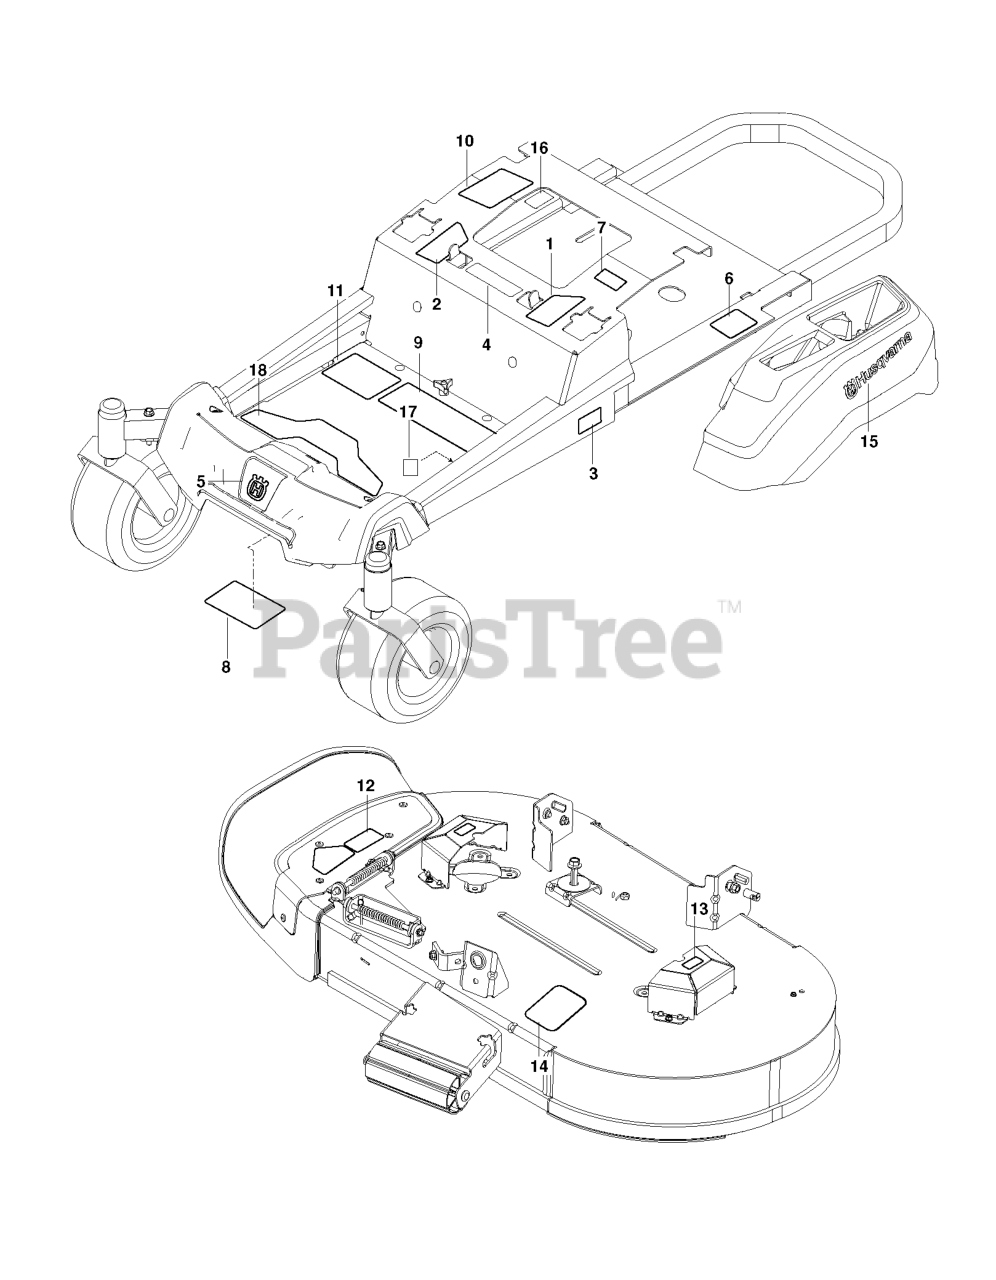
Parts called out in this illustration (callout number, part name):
1	DECAL.ZTR.RZ.THRTL/PRKBRK.V2.L
2	DECAL.ZTR.RZ.THRTL/PRKBRK.V2.R
3	DECAL.ZTR.SIDRAIL.Z242F.HUS
4	EURO DECAL-BATTERY WARNIN6
5	DECAL.BADGE.55MM.CROWNH.HUSQ
6	DECAL, DO NOT TOW
7	DECAL, EXITING MOWER
8	DECAL, SERVICE
9	DECAL.ZTR.WARNING.SMARTIGNITIN
10	DECAL, CUSTOMER RESPNSIBILITY
11	DECAL.ZTR.STARTINSTRCT.CHOKE15
12	DECAL.TRACT/ZTR.DECKWARN.HUSQ
13	DECAL.DECK.6MIL.EURO.NOSTEP
14	DECAL.V-BELT.SCH.42/46"MEC/ELE
15	DECAL.HUSQVARNA.210MM
16	DECAL CERTIFICATION DECAL EMCC
17	DECAL.80.DBA.AUSTRALIA
18	PAD.RZ.FOOTREST.PLATE
